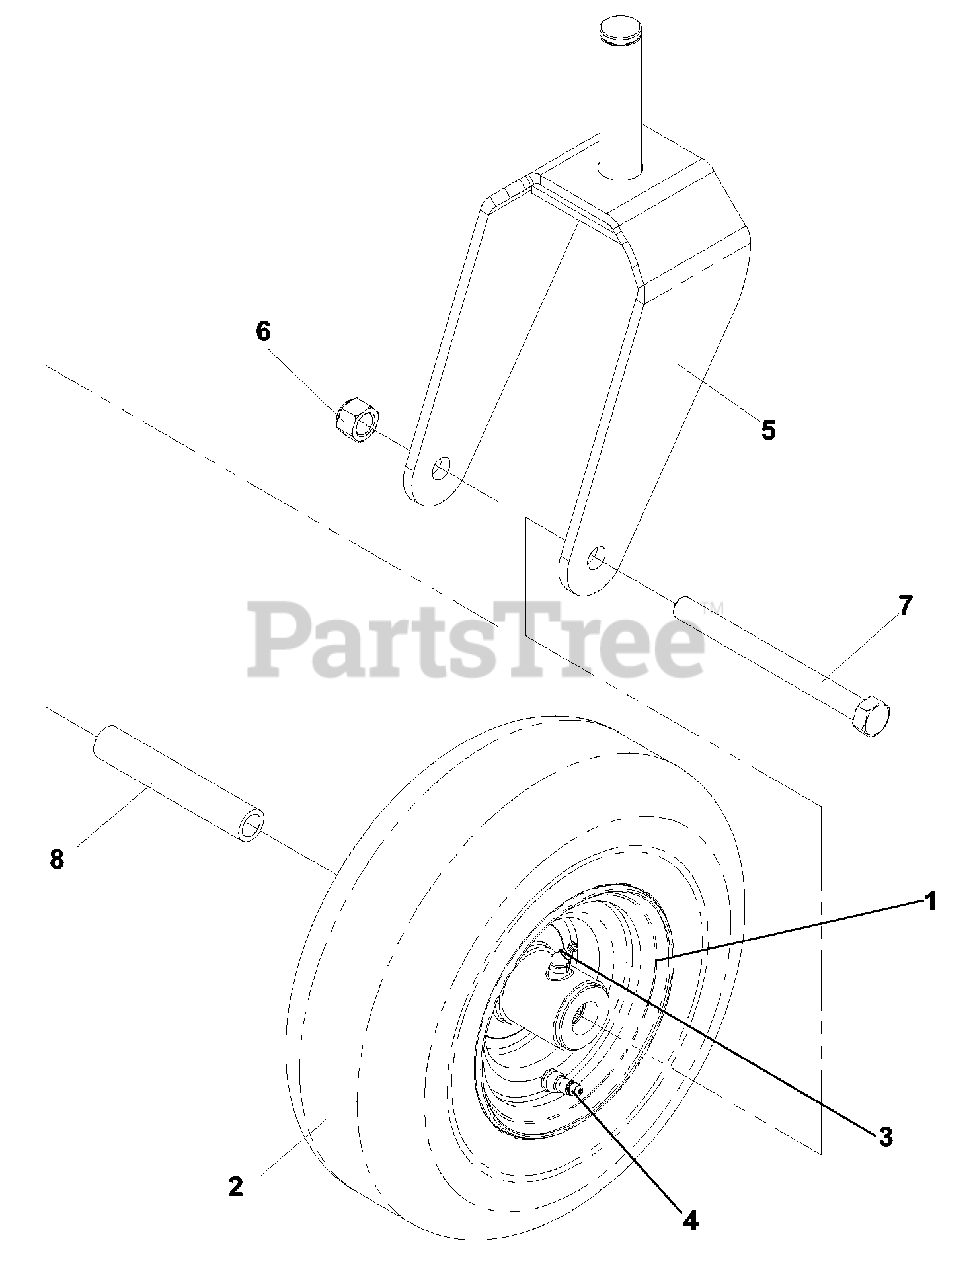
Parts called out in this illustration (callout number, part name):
2	TIRE 410/350-5, 4 PLY
3	ZERK
4	VALVE STEM
5	CASTER WELDMENT
6	NUT 1/2C, NYLOC
7	HCS 1/2C X 5 1/2
